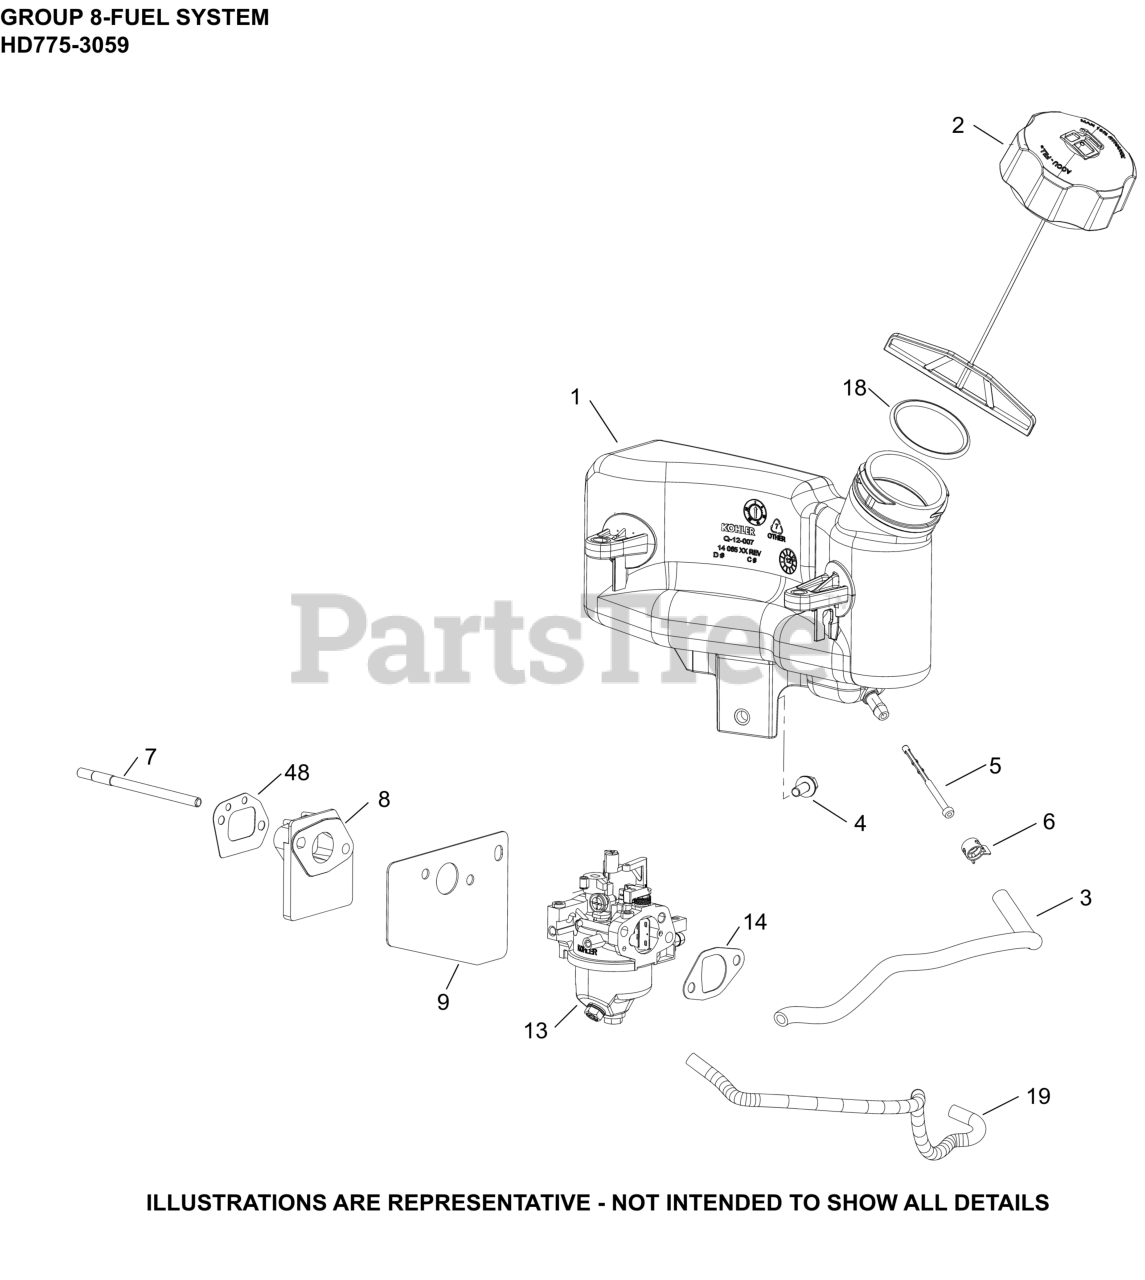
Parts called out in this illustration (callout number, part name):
1	TANK, FUEL 1.4L FOR EUROPE ONLY
2	CAP ASSEMBLY, FUEL
3	HOSE, FUEL LOW-PERMEATION
4	SCREW, HEX FLANGE (M6)
5	FILTER, FUEL IN-NIPPLE
6	CLAMP, HOSE (NON-CALIF)(#1423710S)
7	STUD,M6X1.0X100.2MM
8	KIT, SPACER
9	KIT, CARBURETOR HEAT SHIELD GASKET
13	KIT, CARBURETOR 13 MM STD CHOKE
14	KIT, INTAKE GASKET
18	SEAL, FUEL CAP- (#DSC)
19	HOSE, EVAPORATIVE
48	GASKET SPACER
NI	KIT,HIGH AL(4000-8000 FT)USE 14 755 04-S
NI	KIT, CARBURETOR REPAIR (RUIXING)
